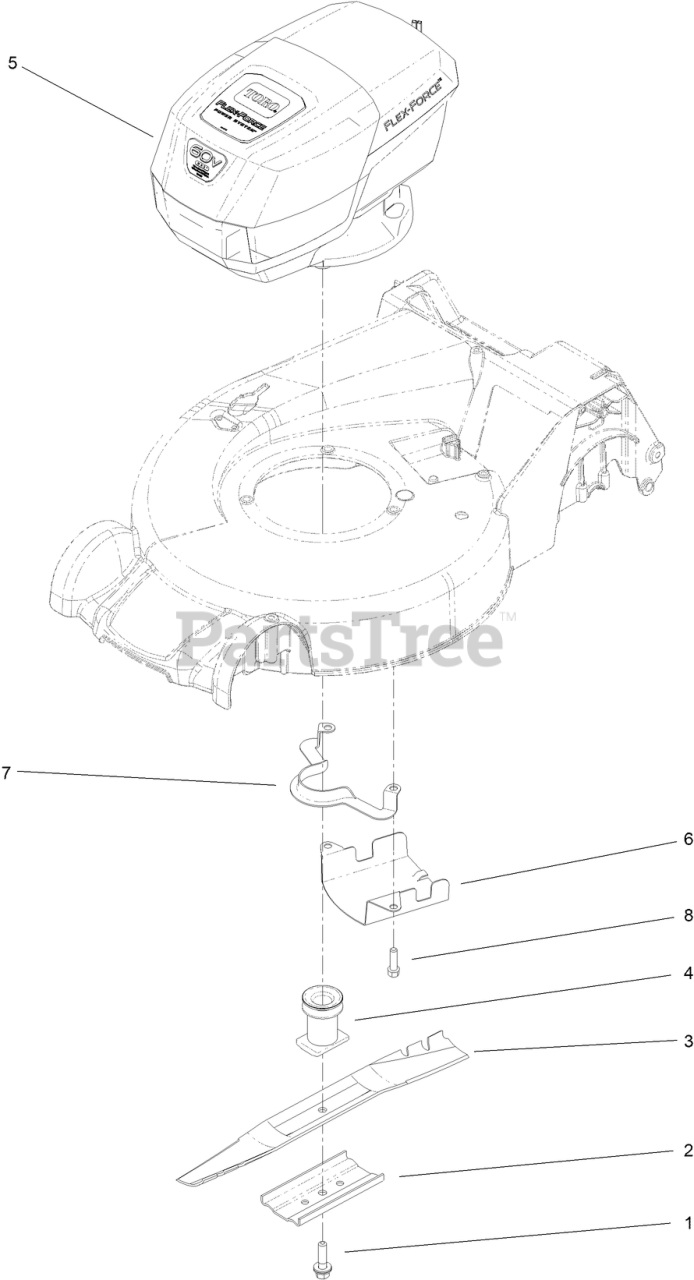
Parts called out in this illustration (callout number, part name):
1	BOLT-BLADE
2	SUPPORT-BLADE
4	DRIVER-BLADE
5	MOTOR MODULE
6	SHIELD-GRASS
7	GUIDE-BELT
